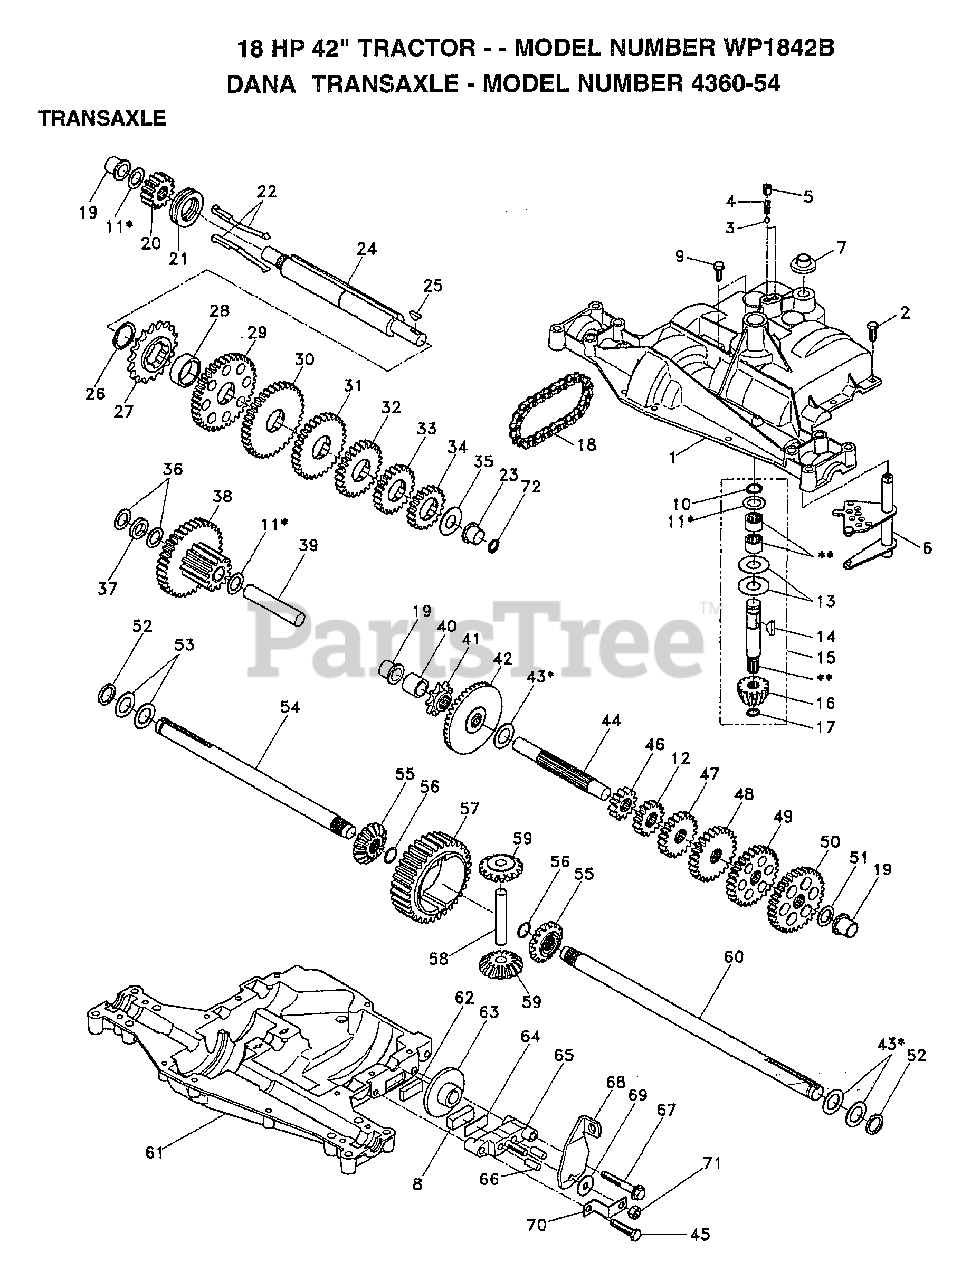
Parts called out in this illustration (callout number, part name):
4	"SPRING, DETENT LT"
5	"SCREW, SET LT"
6	SHIFTER.ASM.KIT.
7	SHIFTER BOOT
8	PUCK T
9	SCREW TAP W/SEAL
10	RETAINING RING LT
11	ASM KIT SHIM 4689
13	WASHER T
14	WOODRUFF KEY
17	"RING,RETAINING LT"
18	"CHAIN,24 PTCH LT"
19	BEARING.FLNG.5510
20	GEAR SPUR 14T
21	COLLAR CLUTCH
22	KIT.ASM.CLUTCH KY
23	"FLANGE, BEARING"
24	SHAFT INTERM
25	WOODRUFF KEY
26	"RING,RETAINING LT"
27	SPROCKET 18T T
28	SPACER YT
29	KIT.GEAR.12/37TH
31	GEAR SPUR 30T
32	GEAR 25T LT
33	GEAR SPUR 22 TT
34	SPUR GEAR 19T
35	"WASHER, PLAIN LT"
36	WASHER 025
37	SPACER
38	ASSM GEAR COMB
39	SHAFT IDLER
40	SPACER T
41	SPROCKET 9T LT
43	ASM KIT SHIM
44	SHAFT T
45	"SCREW, TAPPING LT"
48	"GEAR, SPUR 25T LT"
49	GEAR 28T T
50	"GEAR, SPUR 31T LT"
51	WASHER 060
52	NEOPRENE WASHER
53	WASHER 031
55	GEAR LT
56	"RING,RETAINING LT"
58	SHAFT T
59	"GEAR,MITER 15T YT"
62	PUCK T
63	BRAKE DISC. T
64	SPACER LT
66	PIN T
69	WASHER LT
71	NUT.LOCK.5/16-24
72	SQUARE RING
